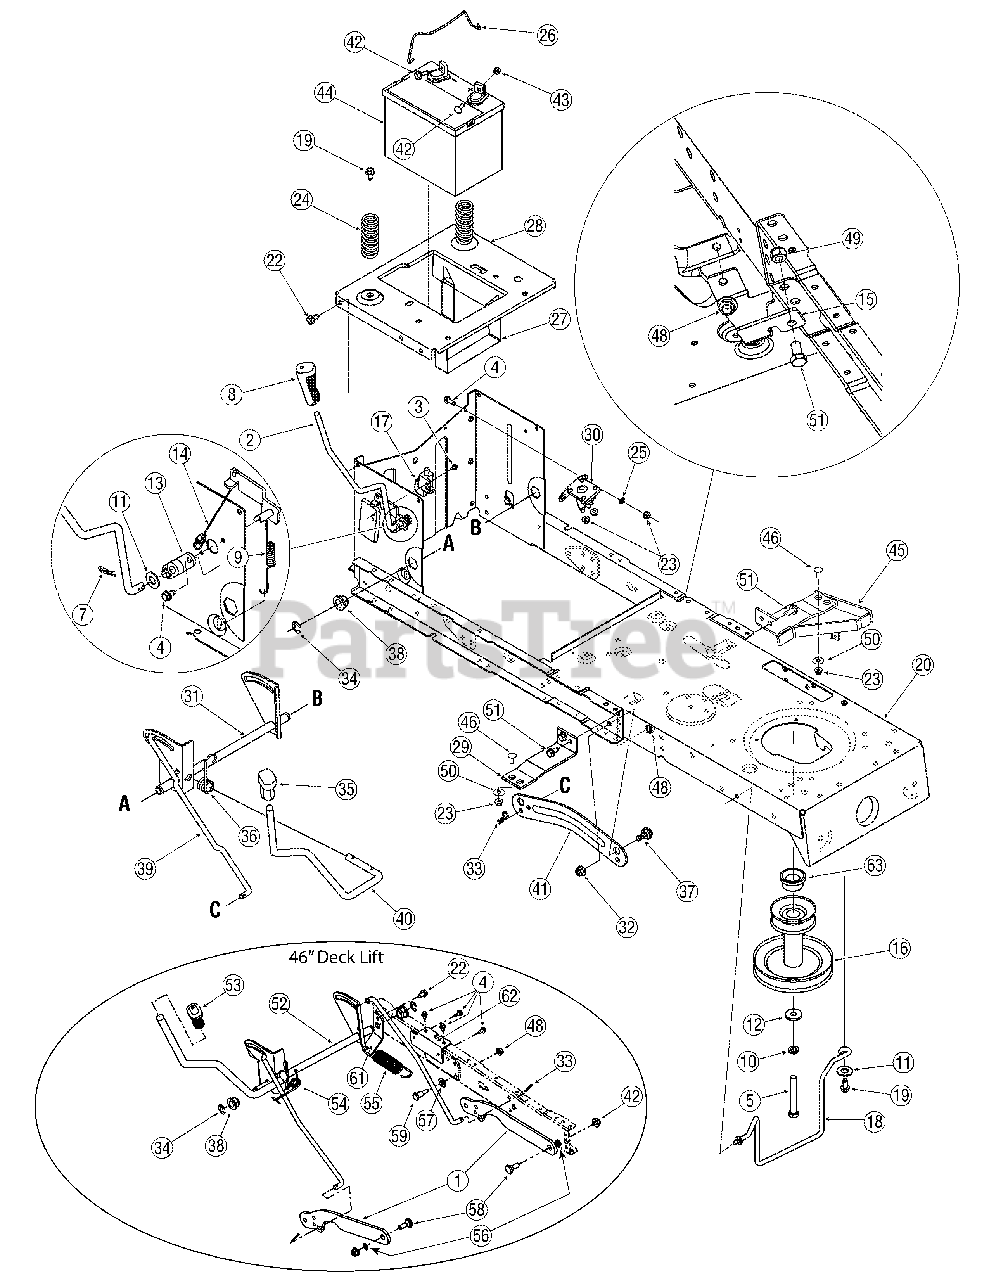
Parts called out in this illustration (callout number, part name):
3	Shoulder Screw, #10-16, 0.500
4	Screw, 1/4-20, 0.500
5	Screw, 7/16-20, 3.25 38 &42" Dk.
5	Screw, 7/16-20, 2.75 46" Deck
7	Pin, Click, .092 x 1.64
8	Grip, Handle, 3/8
9	Spring, Extension
10	Washer, Lock, 7/16
11	Washer, Flat, .406 x .875 x .059
12	Washer, Flat, .450 x 1.250 x .164
13	Bearing, PTO
14	Cable, Deck Engagement
16	Engine Pulley, 38" & 42" Deck
16	Engine Pulley, 46" Deck
17	Switch, Interlock
18	Rod, Belt Keeper (38" Deck)
18	Rod, Belt Keeper (42" Deck)
18	Rod, Belt Keeper (46" Deck)
19	Screw, 5/16-18, .750
21	Screw, 1/4-20, 0.750
22	Screw, 5/16-18, 0.625
23	Nut, Flange Lock, 1/4-20, GrF
24	Spring, Compr. , 1.28 OD x 3.125
25	Washer, Lock, 1/4
30	Solenoid
32	Nut, Flange Lock, 3/8-16, GrF
33	Pin, Cotter .08 x 1.56 Intern. RH
33	Pin, Cotter .080 x 1.25 Intern. LH
34	Ring, E-Type, .625 Dia.
35	Grip, Handle, 1/2
36	Spring, Torsion 38/42" Decks
37	Screw, Shldr. , .625 x .175, 3/8-16
38	Bearing, Hex Flange
40	Deck Handle, Lift, 38/43" Decks
42	Screw, Carriage, 1/4-20, .75, Gr5
43	Nut, Sems, 1/4-20
44	Battery, 190 CCA
44	Battery, 125 CCA
46	Carriage Screw, 1/4-20 x .62
47	Screw, 5/16-18 x .625
48	Flange Lock Nut, 5/16-18
49	Hex Lock Nut, 5/16-18
50	Flat Washer, .28 x .74 x .063
51	Hex Screw, 5/16-18 x .75
53	Grip, Handle, 5/8
54	Spring, Torsion 46" Deck
55	Extension Spring
56	Washer, Flat, .385 x .62 x .063
57	Washer, Flat, .474 x .879 x .064
58	Bolt, Shldr. .500 x .270 3/8-16
59	Screw, Shldr. , .437 x .54
60	Deck Handle, Lift, 46" Deck
61	Lift Bracket
63	Spacer, 1.010 x 1.400 x .825
